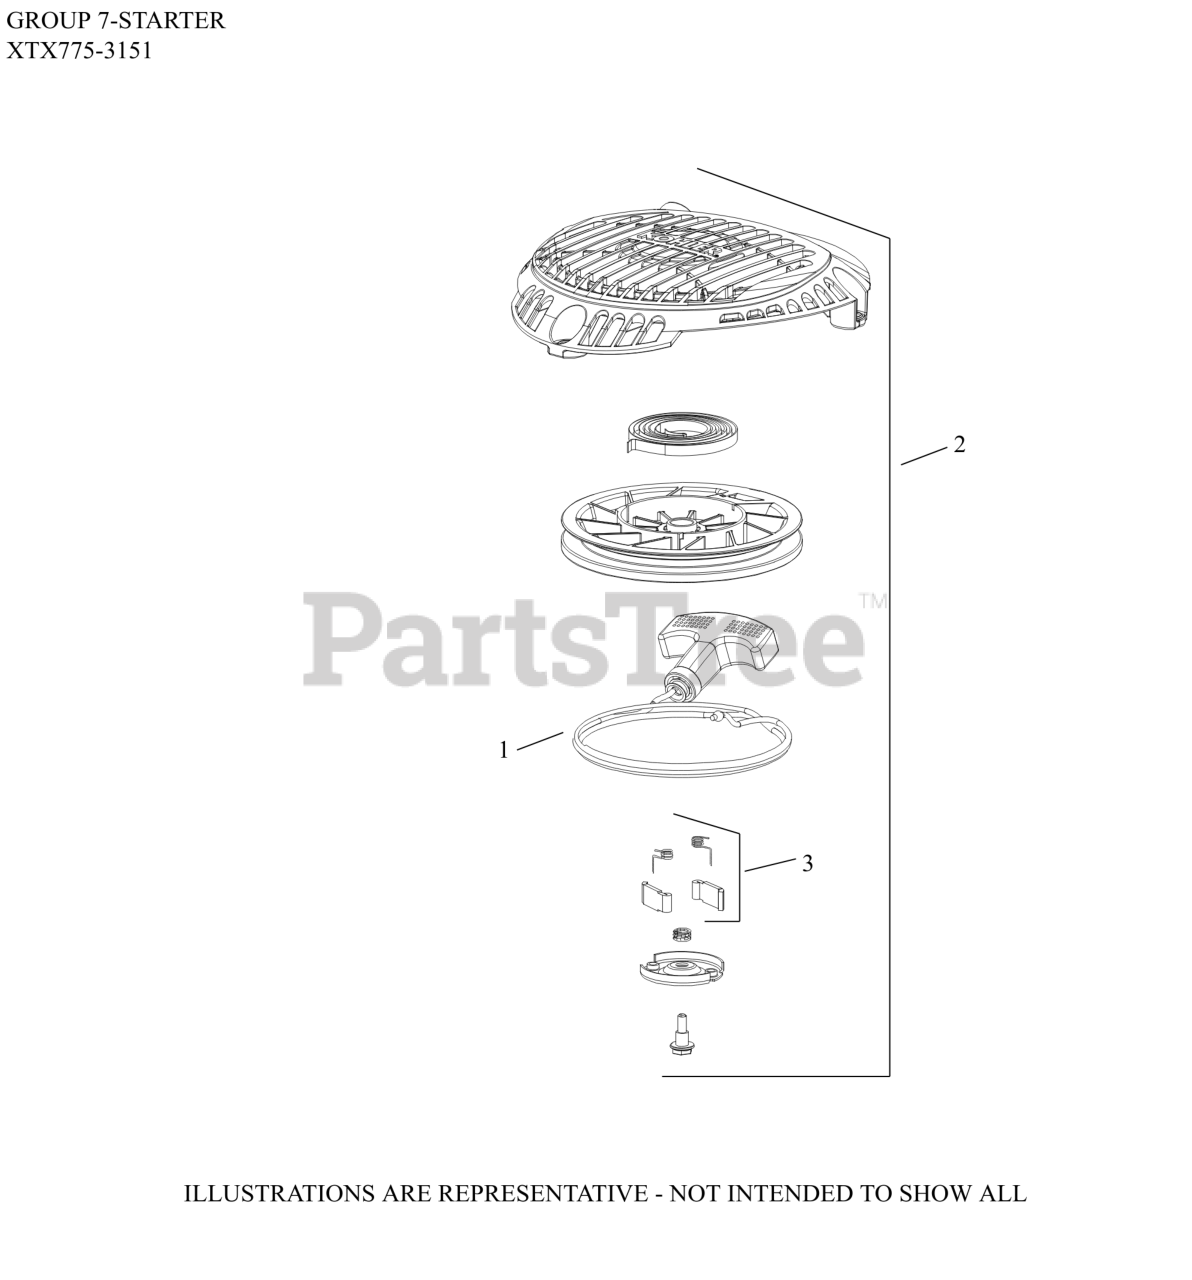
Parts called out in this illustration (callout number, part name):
1	KIT, STARTER ROPE W/HANDLE
2	STARTER ASSEMBLY, RETRACT
3	KIT, PAWL REPAIR
